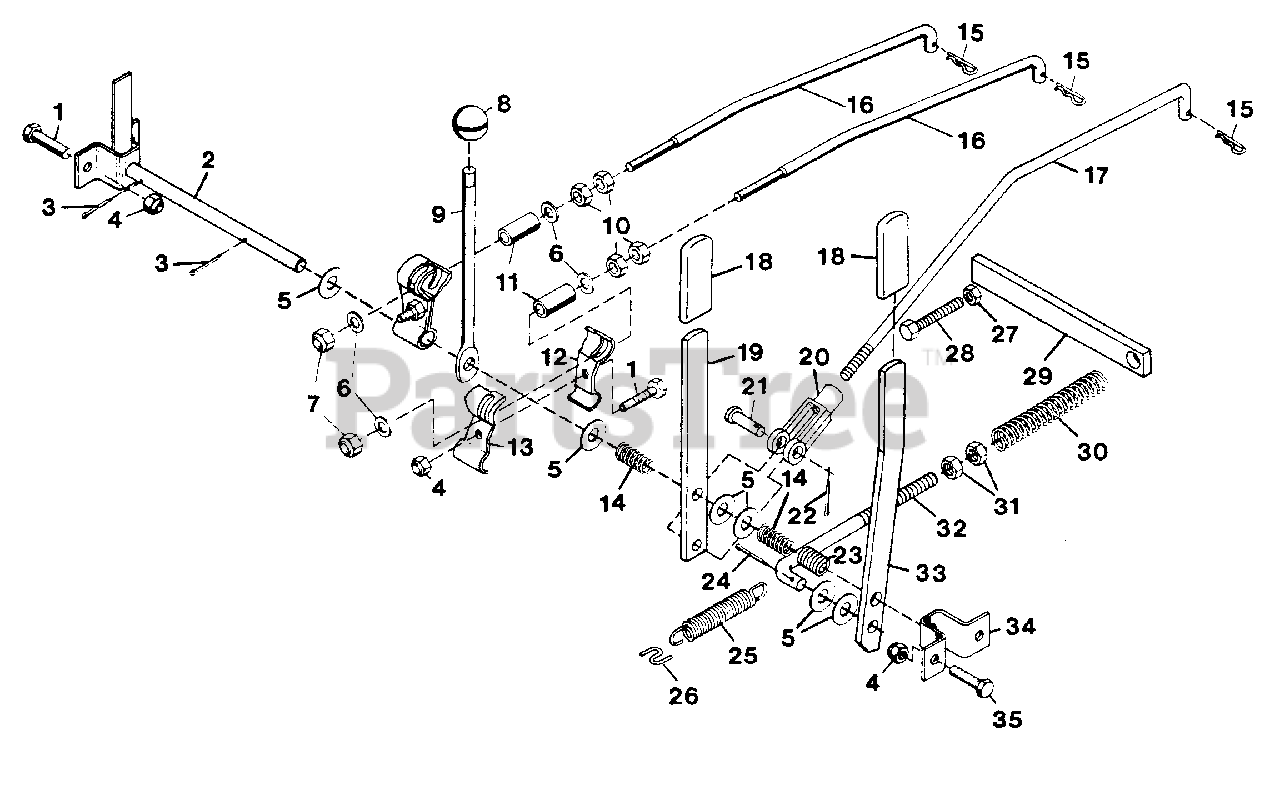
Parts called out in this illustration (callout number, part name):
1	BOLT, HEX 5/16-18X.75
2	WELDMENT, CROSS SHAFT
3	PIN, COTTER .12X1.0
4	NUT, LOCK 5/16-18
5	WASHER, FLAT .531X1.06X.095
6	WASHER, FLAT .438X1.00X.083
7	NUT, LOCK 3/8-16
8	KNOB, CONTROL
9	LEVER, SHIFT
10	NUT, JAM 3/8-16
11	BUSH., ST. .396X.490X1.63 STL.
12	ARM, SHIFTER R.H.
13	ARM, SHIFTER L.H.
14	SPRING, COMP. 2.75X.625X34
15	PIN, COTTER HAIR
16	ROD, SHIFT
17	ROD, 2-SPEED
18	GRIP, HANDLE
19	LEVER, HI-LO SHIFT
20	CLEVIS, 3/8-24 ADJUSTABLE
21	PIN, CLEVIS .375X.948
22	PIN, COTTER .09X.75
23	SPRING, COMP. 1X.78X338
24	PIN, COTTER .125X1.25
25	SPRING, EXTENSION 5.5X.5X20 RATE
26	CLIP, SPRING
27	NUT, HEX 3/8-16
28	BOLT, HEX 3/8-16X2.50
29	SPRING, PTO CLUTCH
30	SPRING, COMP.(PTO LOADING)
31	NUT, JAM 1/2-13 HEX
32	ROD, LIFT
33	LEVER, PTO CONTROL
34	BRACKET, CROSS SHAFT
35	BOLT, HEX 5/16-18X1.00
